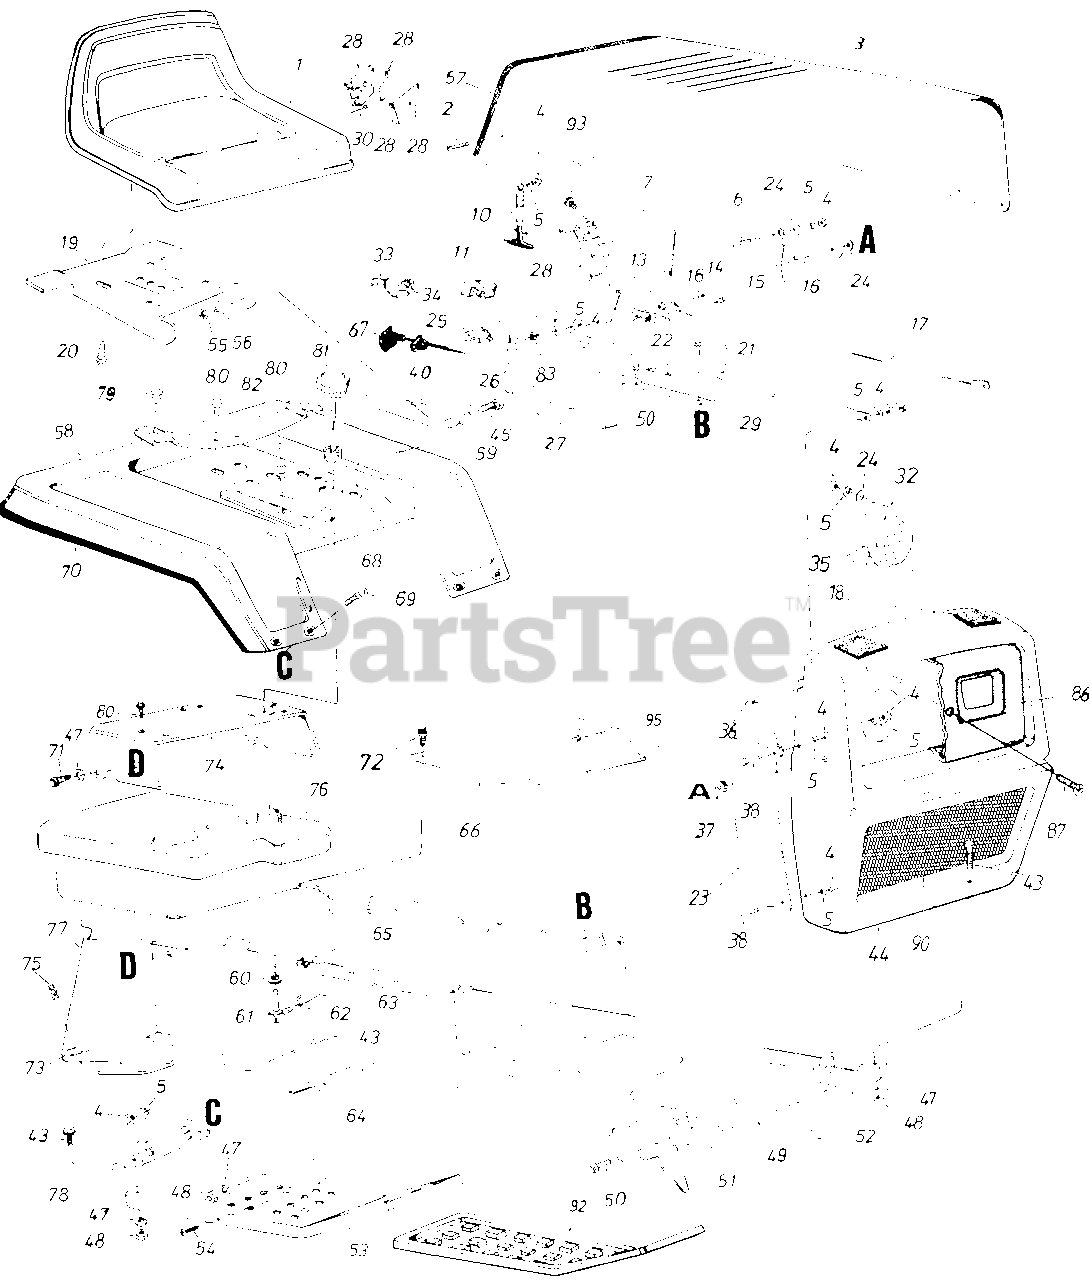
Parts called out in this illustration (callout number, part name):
1	Seat Assembly
2	Truss Mach. Scr. 1/4-20 X .50" Lg.
5	L-Wash. 1/4" Scr.
6	Truss Mach. Scr. 1/4-20 x .50" Lg.
7	Vinyl Molding Strip 29"
10	Hood Latch Ass'y.
11	Ammeter
13	Circuit Breaker 8 Amp.
14	Hex Tap Scr. #10 x .50" Lg.
16	Truss Mach. Scr. 1/4-20 x .75" Lg.
17	Grille Positioning Rod
18	PVC Foam Strip 1/2 X 1.00" x 2.00" Lg.
19	Seat Pivot Brkt.
20	Hex Wash. Hd. AB-Tap Scr. 318 x .75" Lg.
21	Hex Thd. Rolling Scr. 1/4" x .50" Lg.
22	Speed Nut #10Z
23	Grille Side Panel R.H.
24	Fl-Wash. 1/4" I.D.
25	Light Switch
26	Truss Hd. Scr. 1/4-20 x 1.00" Lg.
27	Dash Panel Ass'y.
28	Throttle Control Box Comp.
29	Grille Positioning Rod
30	Throttle Control Cable
32	Head Lamp Retainer
33	Ignition Key
34	Ignition Switch
35	Head Lamp
36	Truss Machine Scr. 1/4-20 x .75" Lg.
37	Rubber Wash. .50" I.D. x 1.00 O.D. x .25 Thk.
38	Truss Mach. Scr. 1/4-20 x .50" Lg.
40	Seat Bracket L.H.
43	Hex Scr. 5/16-18 x .75" Lg.
44	Grille Ass'y.
45	Hex Bolt 5/16-18 x .75" Lg.
47	L-Wash. 5116" I.D.
48	Hex Nut 5/16-18 Thd.
49	Lower Frame Ass'y.
50	Hex Thd. Rolling Scr. 5/16" x.75" Lg.
51	Grille Mount Brkt. R.H.
52	Grille Mount Brkt. L.H.
53	Running Board R.H.
54	Truss Mach. Scr. 5/16-18 x .75" Lg.
55	Hex Cent. L-Nut 5/16-18 Thd.
56	Bell-Wash. .34" I.D. x .88 0 O.D.
57	Vinyl Moulding Strip 30"
60	Bushing
61	90ø Nipple
62	Hose Clamp 3/8"
63	Gas Line 46" Lg.
64	Running Board Rod
65	Speed Nut #10-24
66	Transmission Cover Ass'y.
67	Choke Control Comp.
68	Seat Bracket R.H.
69	Carr. Bolt 1/4-20 x .50" Lg.
70	Trim Strip 81" Lg.
71	Hex Thd. Rolling Scr. 5/16-24 x .75" Lg.
72	Truss Hd. Scr. #10 x .50" Lg.
74	Seat Mounting Channel
75	Internal Cotter Pin
77	Hitch Plate
80	Hex Wash. Hd. Self-Tap Scr. 5/16-18 x .50" Lg.
82	Seat Spring
83	External Wash. 1/4" I.D.
86	Headlight Bezel
87	Hex Wash. Hd. F-Tap Scr. #8-32 x .38" Lg.
90	Grille Screen
93	Truss Mach. AB-Tap Scr. #10 x .50" Lg.
95	Snap Bushing
